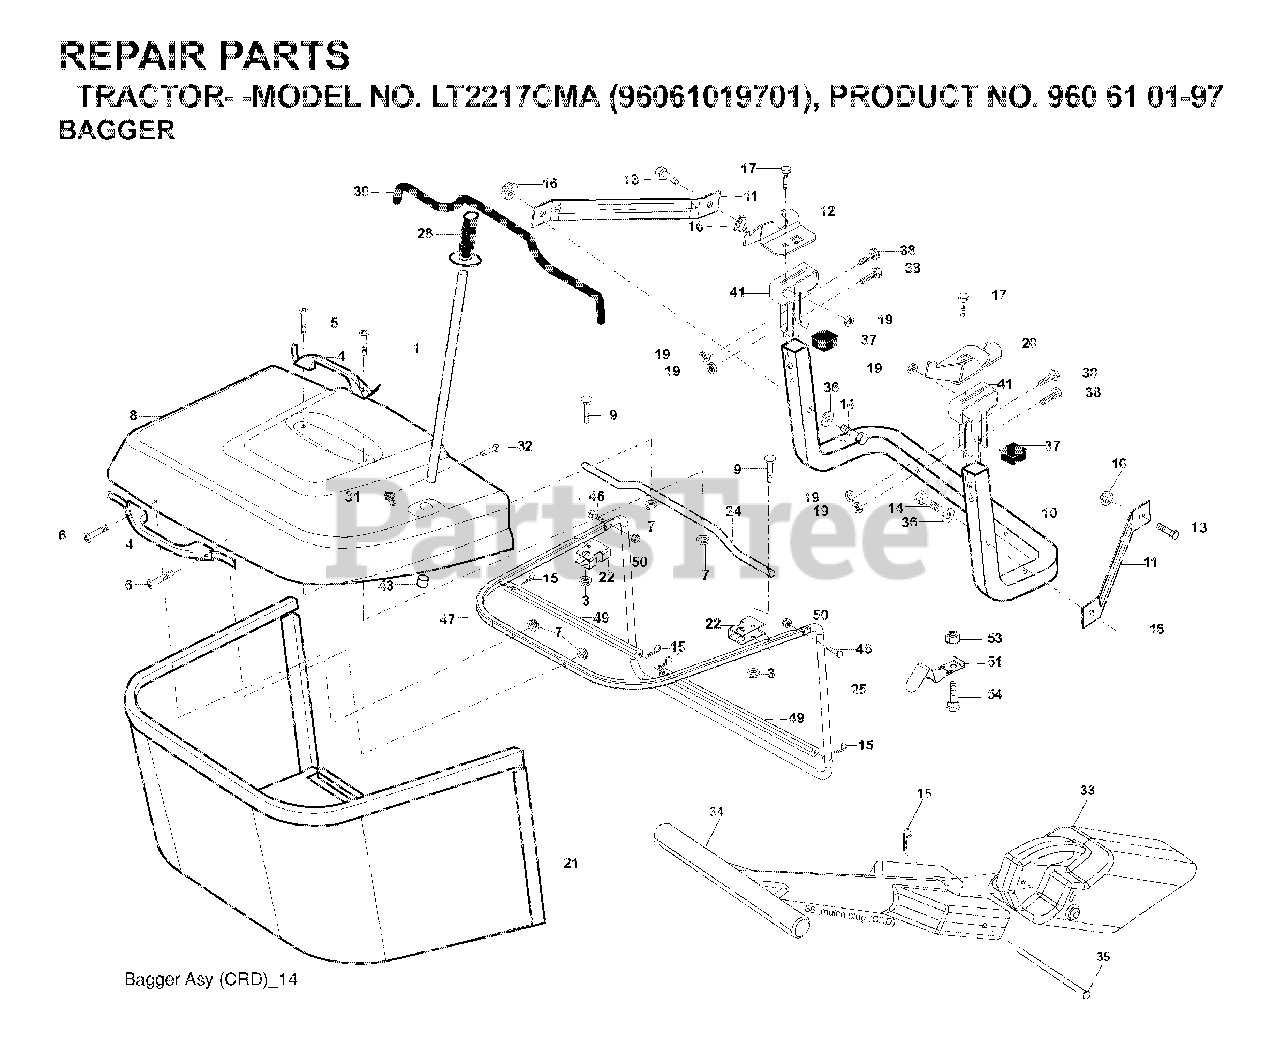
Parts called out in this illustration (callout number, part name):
1	TUBE HANDLE
3	NUT T
5	SCREW.PAN.HEAD
11	BRACKET
14	BOLT-HEX EAK
15	RETAINER-SPRNG RB
16	NUT LOCK FLG 3/8-16 UNC
17	BOLT
19	NUT LOCK HEX FLANGE 5/16-18
20	BRKT.PIVOT.RH.CRD
21	BAGGER.ASM.CRD.2007
22	BRACKET
24	TUBE
28	GRIP.HANDLE.BLACK
31	RETAINER CLIP
32	RIVET,DRILLED
33	PLUG
35	PIN
38	BOLT.5/16-18X2.5
41	BRKT, BAGGER
43	PLUG, TUBING END
46	BOLT.CARRIAGE.5/16-18
50	NUT.71038.31-18.HEX.NYLOCK
53	NUT
54	BOLT
